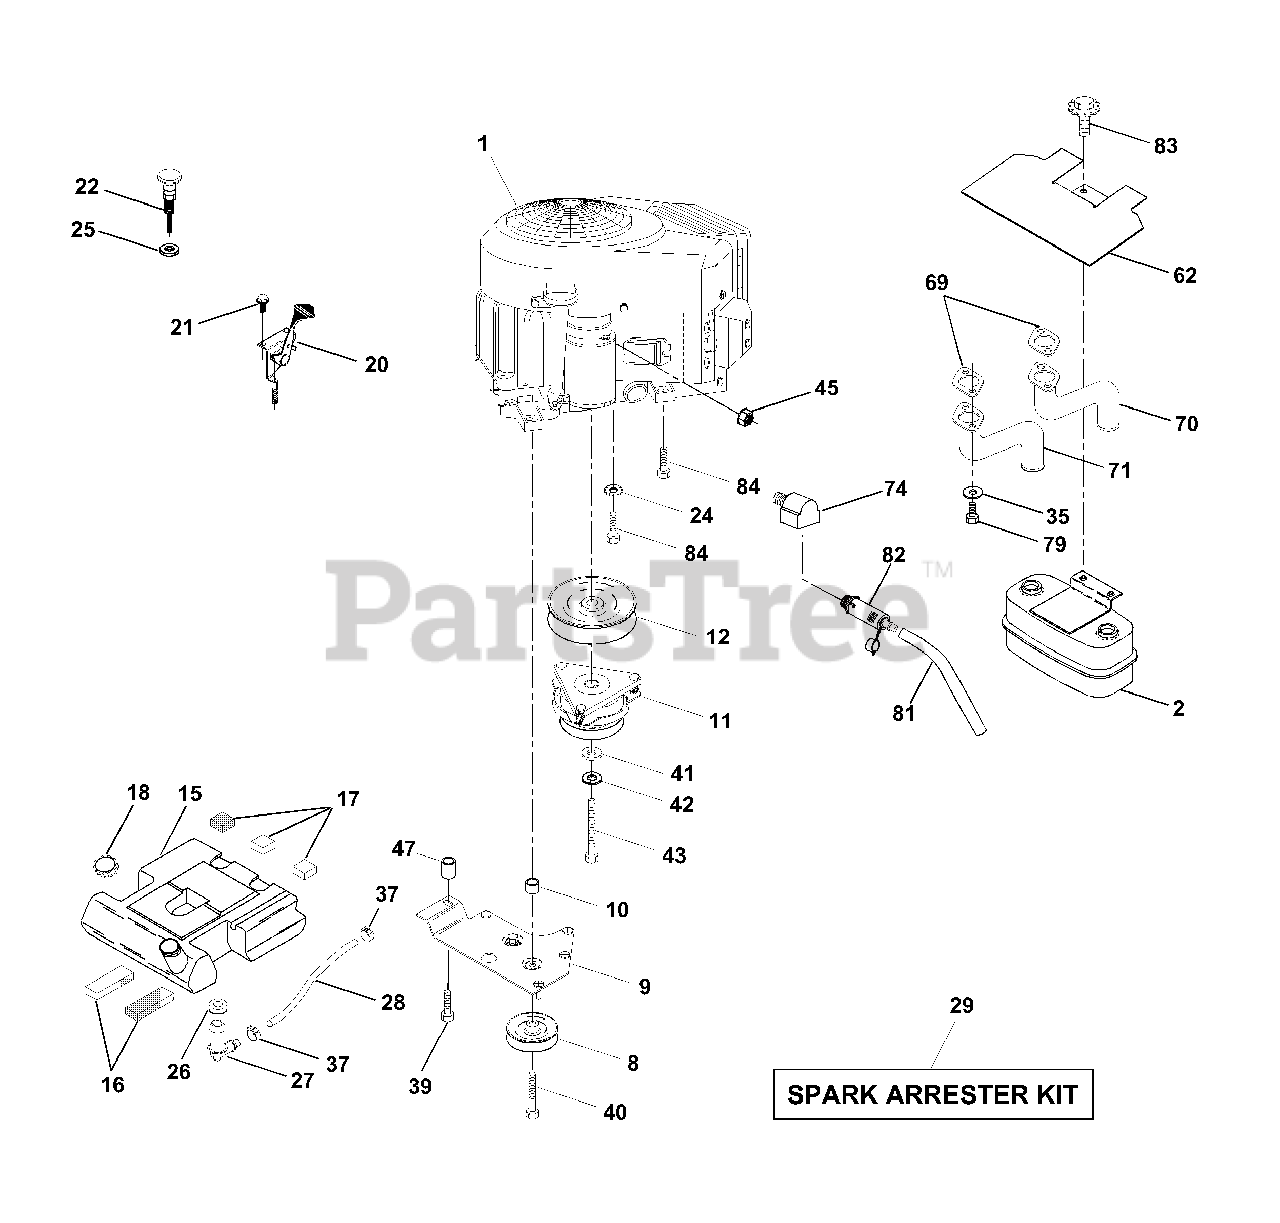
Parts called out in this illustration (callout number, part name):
2	Muffler
8	Pulley V-Idler
9	Keeper Asm Belt Engine Vgt 96
10	Bushing
11	Clutch Electric
12	Pulley Engine Grnd Drive
15	Tank Fuel Rear 3.50 YT/GT
16	Pad Spacer
17	Pad Spacer
18	Cap Asm Fuel Top Vent N/Lany
20	Control Throttle
21	Screw HWHD Hi-Lo #13-16 x 3/4
22	Control Choke
24	Lockwasher Ext Tooth 3/8
25	Nut Keps 3/8-24 UNF
26	Bushing
27	Stem Tank Fuel
29	Spark Arrester Kit
35	Washer Lock Hvy HLCL Spr. 5/16
37	Clamp Hose
39	Screw 3/8 - 16 x 2-1/4 UNC TT
40	Screw 3/8 - 16 x 4 UNC TT
41	Washer 1-1/2 OD X 15/32 ID X .250
42	Washer Lock 7/16
43	Bolt Hex 7/16-20 x 4 Gr. 5-1.5 Thr.
45	Nut Keps Hex 1/4-20 Unc
47	Bushing
62	Shield Heat Muffler
69	Gasket Muffler
70	Tube Exhaust LH
71	Tube Exhaust RH
74	Elbow Street Brass
79	Screw Hex Hd Cap 5/16-18 x 3/4
81	Tube Drain Oil Easy
82	Plug Oil Drain Easy
83	Bolt 5/16-18 Unc x 3/4 w/Sems
84	Screw Thdrol 3/8-16 x 1-1/2
